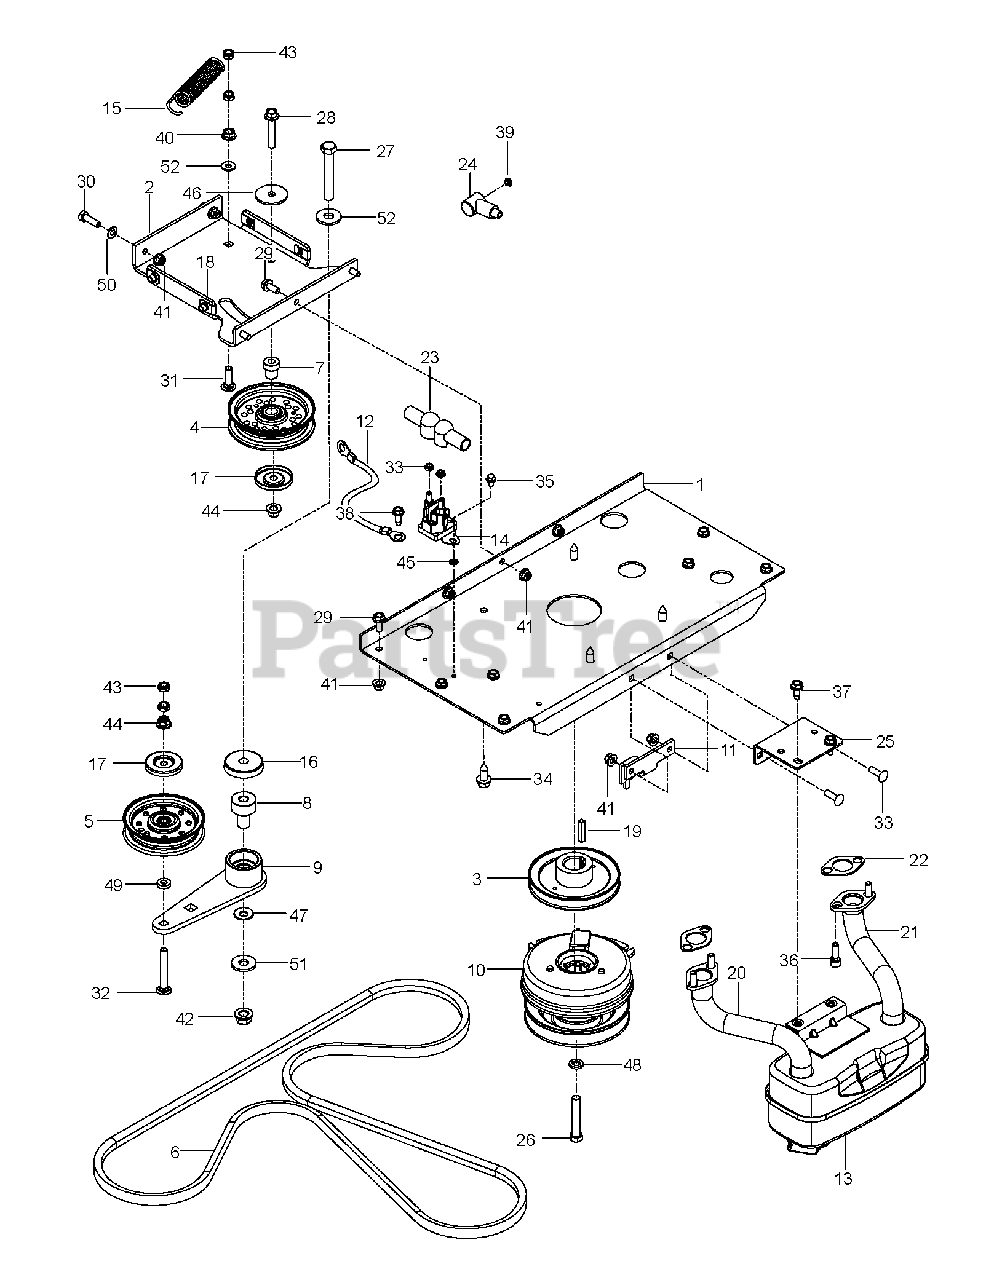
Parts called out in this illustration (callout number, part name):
1	PLATE.PNT.ENGINE.E-DIP
2	PLATE, IDLER, BLK
3	PULLEY, V, 1.125 BORE
4	IDLER PULLEY
5	PULLEY.IDLER.FLAT.46.PR.DR.
6	BELT, HYDRO, 3400
7	PIVOT, IDLER
8	PIVOT, BEARING
9	ARM, IDLER, STEEL, W/BGS
10	CLUTCH 200 FT LB
11	STOP, CLUTCH, BLACK
12	CABLE POSITIVE
13	MUFFLER ASM TWIN
14	SOLENOID.STARTER.BRASS.PLUNGER
15	SPRING, PUMP
16	SHIELD, DUST
17	DUST SHIELD
18	U-CLIP 5/16-18 NUT RETAINER
19	KEY, 1/4 SQ X 1 1/4
20	EXHAUST.TUBE.LH.BS/TWIN
21	EXHAUST.TUBE.RH.B&S.TWIN.INTEK
22	GASKET.MUFFLER.B&S.REF #273485
23	TERMINAL COVER
25	U-CLIP 5/16-18 NUT RETAINER
25	BRKT, MUFFLER, BLK
26	CLUTCH BOLT7/16-20X2.5 GR596HR
27	HCS 1/2C X 3 1/4
28	HHFS 3/8-16 X 2.0 GD 5
29	HHFS 5/16-18 X 3/4
30	BOLT.FIN.HEX.5/16-18UNC X 1.00
31	BOLT.3/8-14X1.25
32	BOLT
34	SCREW 3/8-16X1
35	RP_SCREW.1/4-20X3/8
36	SCREW.SOCKET.HEAD.5/16-18
37	SCREW
38	SCREW 14-20 X 5/8
39	JAM NUT 1/4C (2 2 PW01)
40	NUT 3/8C WHIZ
41	5/16-18 NYLOC FLANGE NUT
42	NUT, 1/2-13 HEX FLG NYLOC ZD
43	NUT HEX 3/8-16 NYLON, THIN
44	NUT 3/8-16 HEX FLG NYLOC ZD
45	WASHER 1/4 INT TOOTH
46	WASHER, 3/8 SPEC
47	CONTACT BELLSPR 1/2
48	WASHER 7/16 LOCK
49	WASHER 3/8 X 3/4 X .187 TK
50	WASHER
51	WASHER.9/16 X 1 3/8 X 12 GA.
52	WASHER 3/8 FLAT
